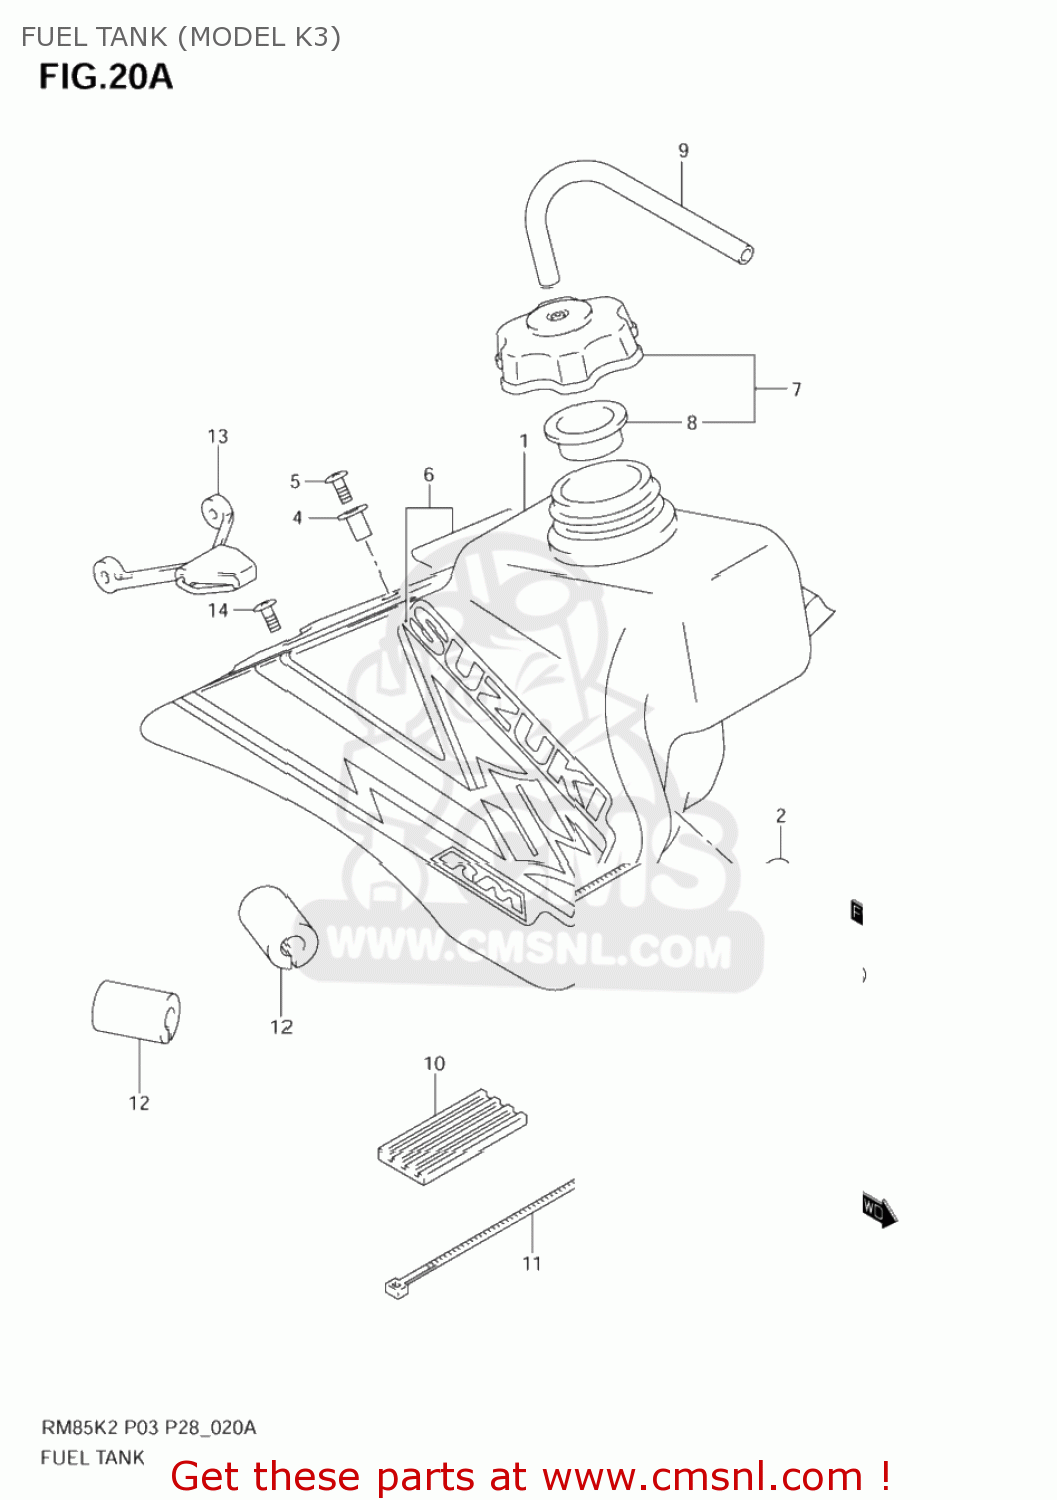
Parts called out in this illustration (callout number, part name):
1	TANK,FUEL
2	BRACKET,FUEL TANK FR
3	SCREW
4	HOOK,SEAT FR
5	SCREW
6	TAPE SET,FUEL TANK
7	CAP SET,FUEL TANK
8	GASKET,CAP (NAS)
9	HOSE(5X8.2X600)
10	CUSHION,FUEL TANK UPR FR
11	CLAMP(L:250)
12	CUSHION,FUEL TANK UPR RR
13	BAND,FUEL TANK RR
14	SCREW
15	SPACER(6.5X9X13.5)
16	CUSHION,MUFFLER
17	BOLT(6X25)
